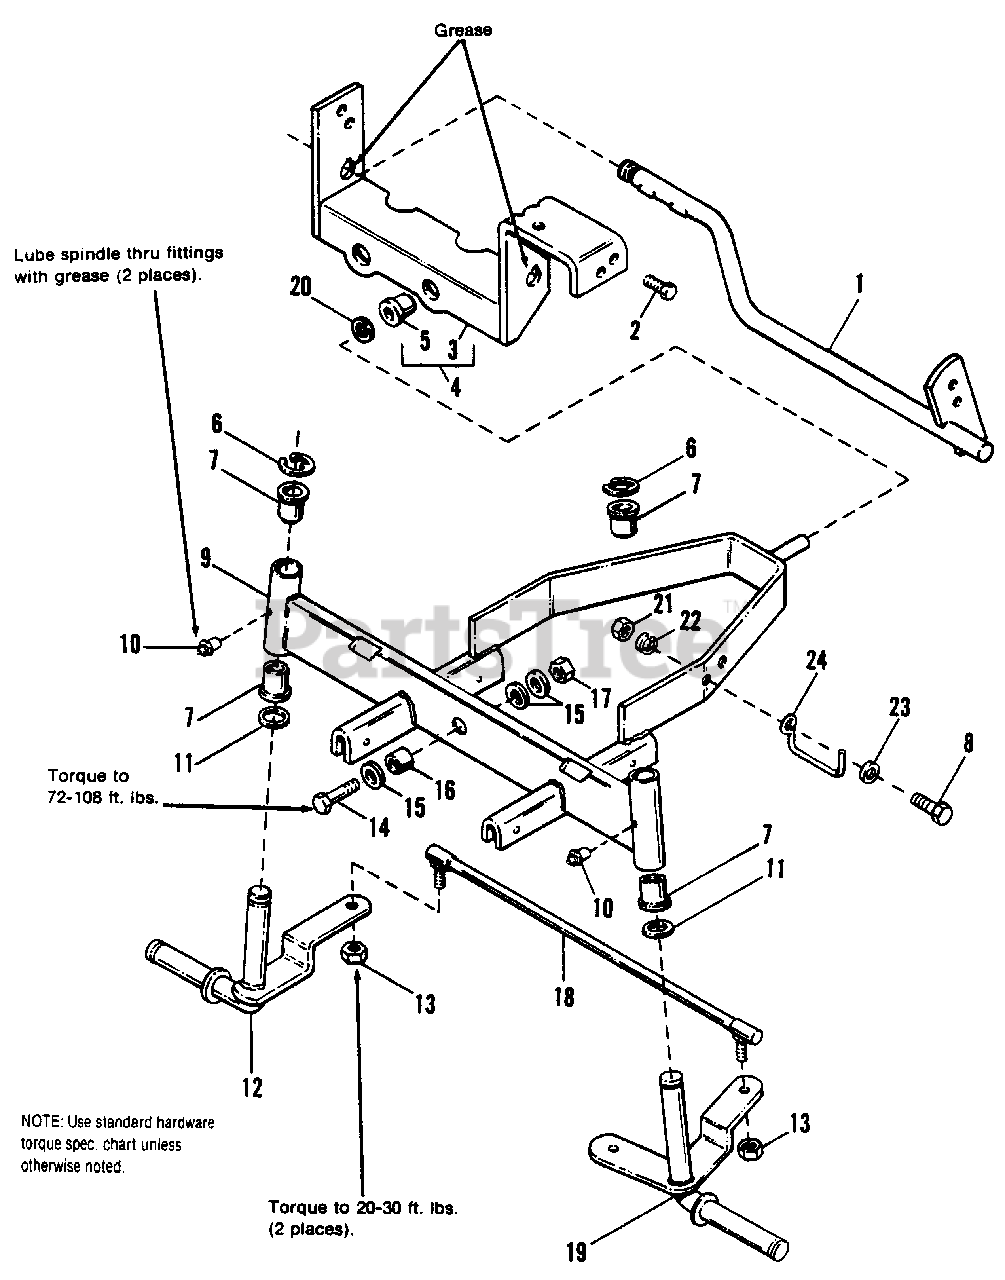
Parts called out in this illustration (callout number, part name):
1	LEVER ASSY., Brake
2	SCREW, Taptite, 5/16-18 x 3/4
4	SUPPORT ASSY., Rear (Incl. Ref. No. 3 & 5)
6	"E" RING, Ext. 3/4
8	CAPSCREW, Hex, 5/16-18 x 1
9	AXLE ASSY., Front (Incl. Ref. No. 7)
10	FITTING, Drive, Type
12	SPINDLE ASSY., R.H.
13	LOCKNUT, Hex, 3/8-24
14	CAPSCREW, Hex, 1/2-13 x 1-3/4
15	WASHER, 9/16
16	SPACER
17	LOCKNUT, Hex, 1/2-13
18	TIE ROD ASSY.
19	SPINDLE ASSY., L.H.
20	WASHER, 5/8
21	NUT, Hex, 5/16-18
22	LOCKWASHER, 5/16
23	WASHER, 5/16
24	GUIDE, Drag Link
